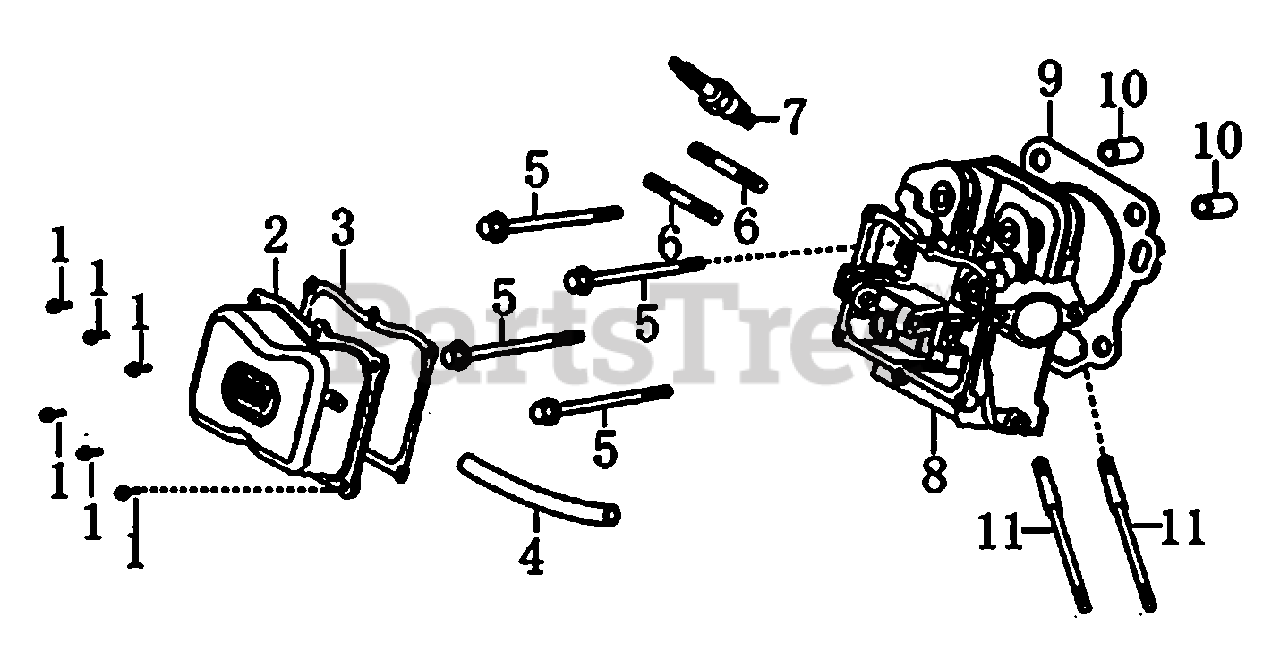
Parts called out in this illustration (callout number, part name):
1	BOLT, FLANGE
2	COVER, VALVE
3	GASKET, VALVE COVER
4	TUBE, BREATHER
5	BOLT, FLANGE, 10X80
6	STUD, EXHAUST
7	SPARK PLUG
8	HEAD, CYLINDER
9	GASKET, CYLINDER HEAD
10	PIN, DOWEL
11	STUD, INTAKE
